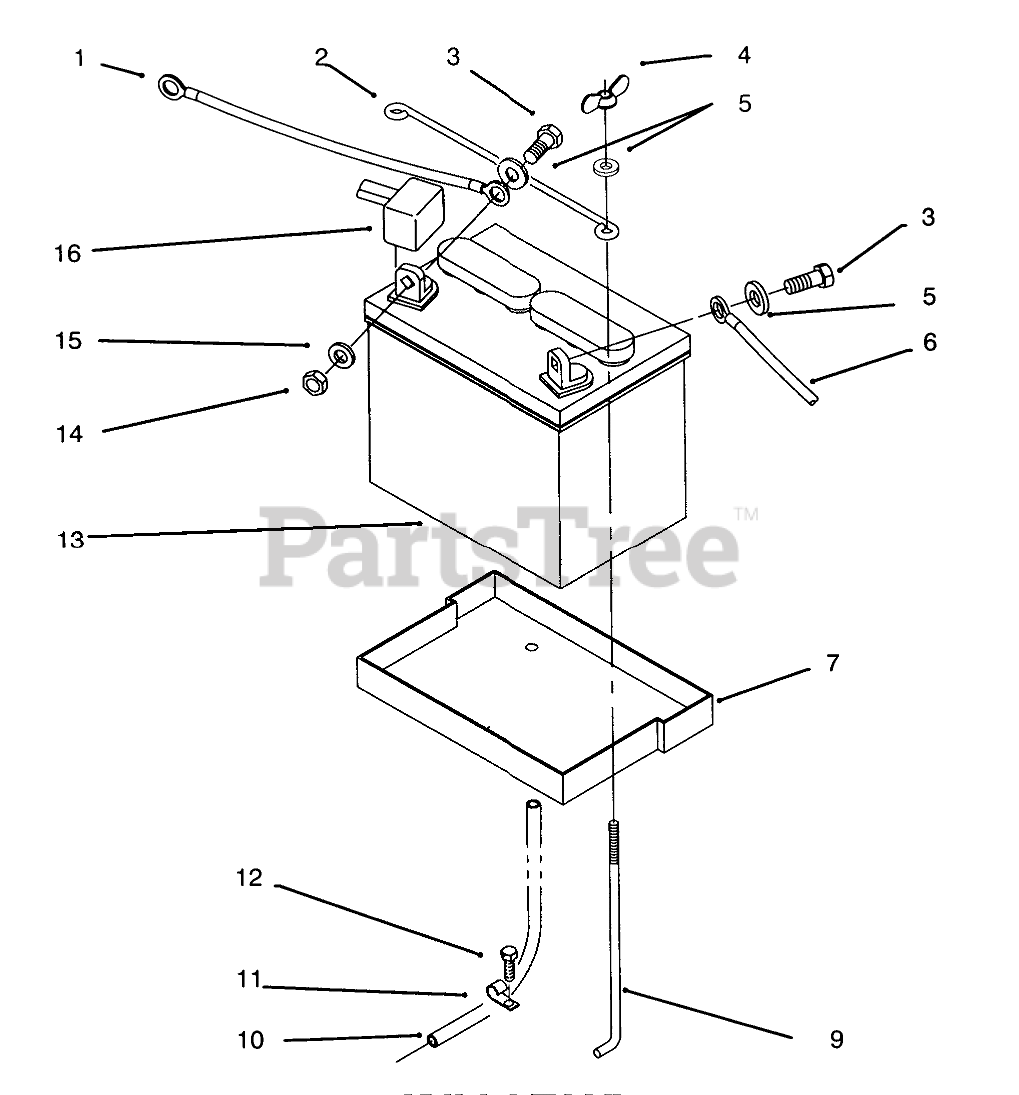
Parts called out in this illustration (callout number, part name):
1	ASS'Y-WIRE
2	HOLDDOWN-BATTERY
3	SCREW-HH
4	NUT-WING
5	WASHER-FLAT
6	ASSY WIRE
7	TRAY-BATTERY
9	HOOK-BATTERY RETAIN
10	TUBE-21" BATTERY DRAIN
11	CLIP
12	SCREW-HH
13	Battery
14	NUT-LOCK, NI
15	WASHER-LOCK
16	Boot
